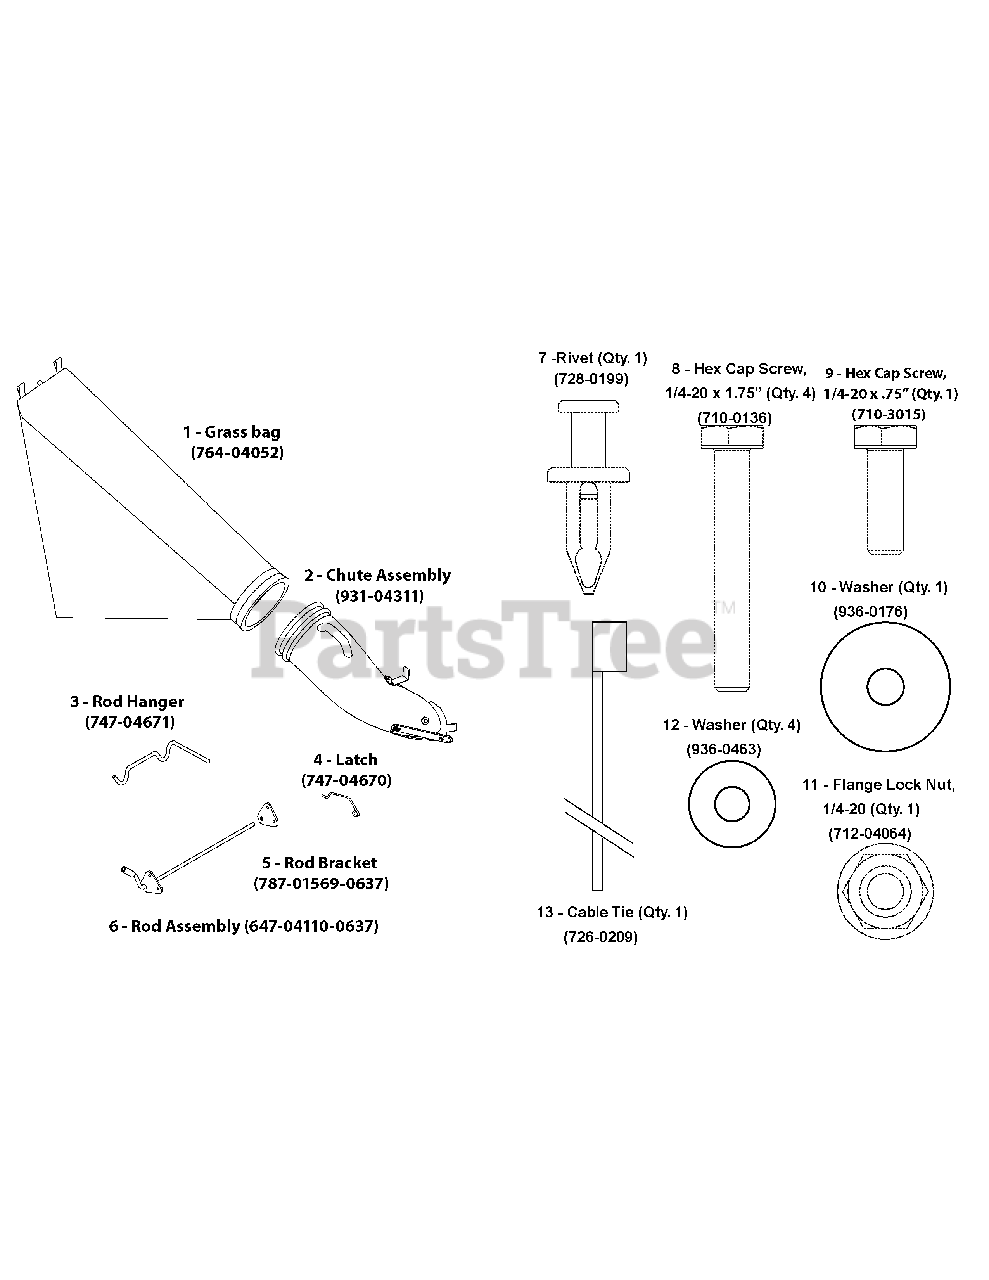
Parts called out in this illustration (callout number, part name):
1	Grass Bag
2	Chute Assembly
3	Rod Hanger
5	Rod Bracket
6	Rod Assembly
7	Rivet
8	Screw Hex 1/4-20 X 1.75
9	Screw, Hex Cap 1/4-20 x .75
10	Washer
11	Flange Lock Nut 1/4-20
12	Washer
13	Tie Cable 29 3/4"
